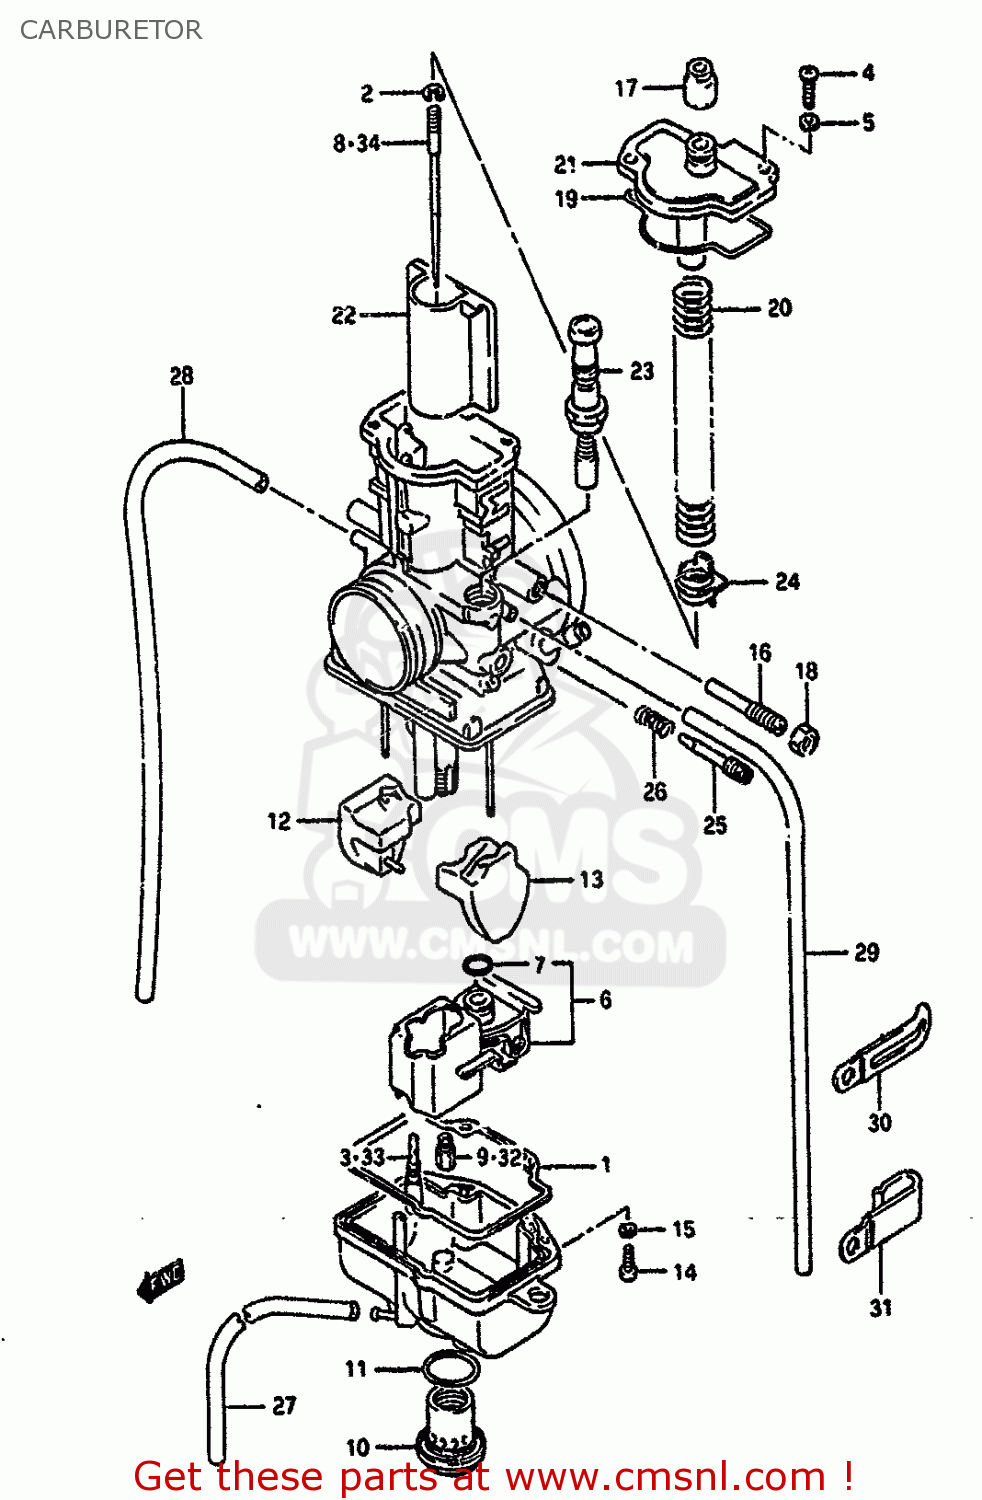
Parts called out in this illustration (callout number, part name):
1	O RING,FLOAT CHAMBER
2	CLIP,NEEDLE
3	JET,PILOT(55)
4	SCREW
5	LOCK WASHER
6	VALVE ASSY,NEEDLE
7	O-RING,NEEDLE VALVE
8	NEEDLE,JET(6AEJ02-65)
9	JET,MAIN(330)
10	CAP,DRAIN
11	O RING
12	FLOAT,R
13	FLOAT,L
14	SCREW
15	LOCK WASHER
16	ADJUSTER
17	CAP
18	NUT
19	O RING,TOP CAP
20	SPRING
21	CAP,TOP
22	VALVE,PISTON
23	PLUNGER ASSY
24	RING
25	SCREW,AIR
26	SPRING
27	HOSE(3X5X600)
28	HOSE(3.5X6.5X600)
29	HOSE(3.5X6.5X600)
30	CLAMP
31	CLAMP
32	JET,MAIN(290)
33	JET,PILOT(45)
34	NEEDLE,JET(6AEJ02-63)
